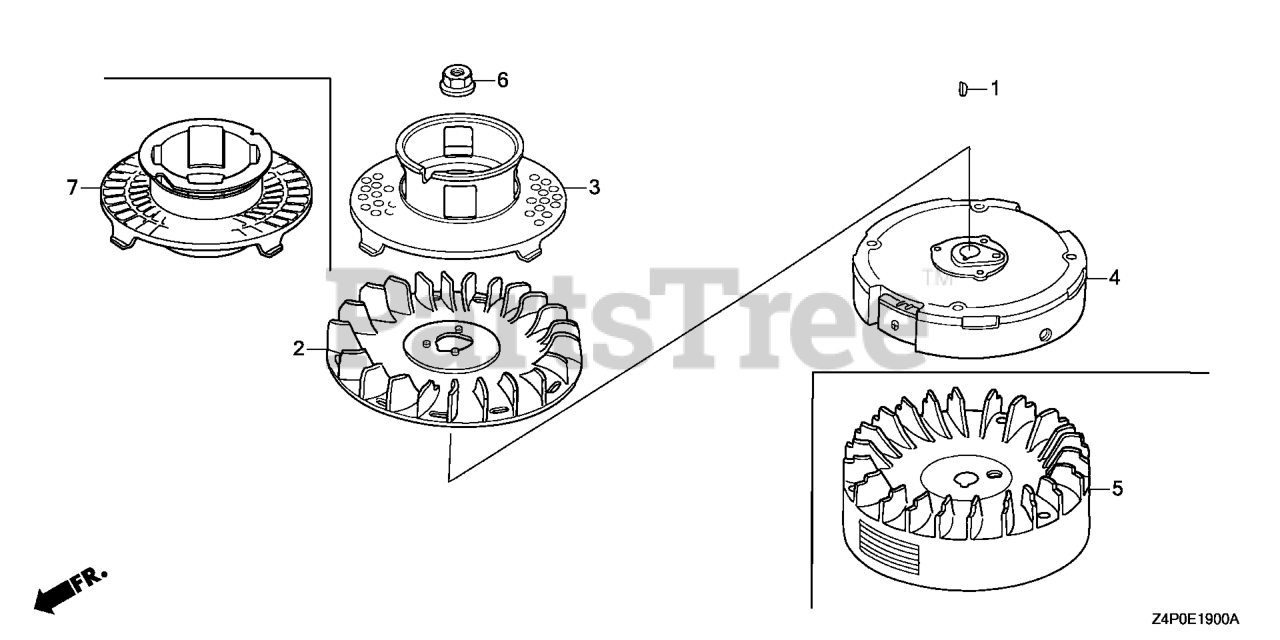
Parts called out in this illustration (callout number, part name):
1	KEY, SPECIAL WOODRUFF (25X18)
2	FAN, COOLING
6	NUT, SPECIAL (14MM)
7	PULLEY, STARTER
